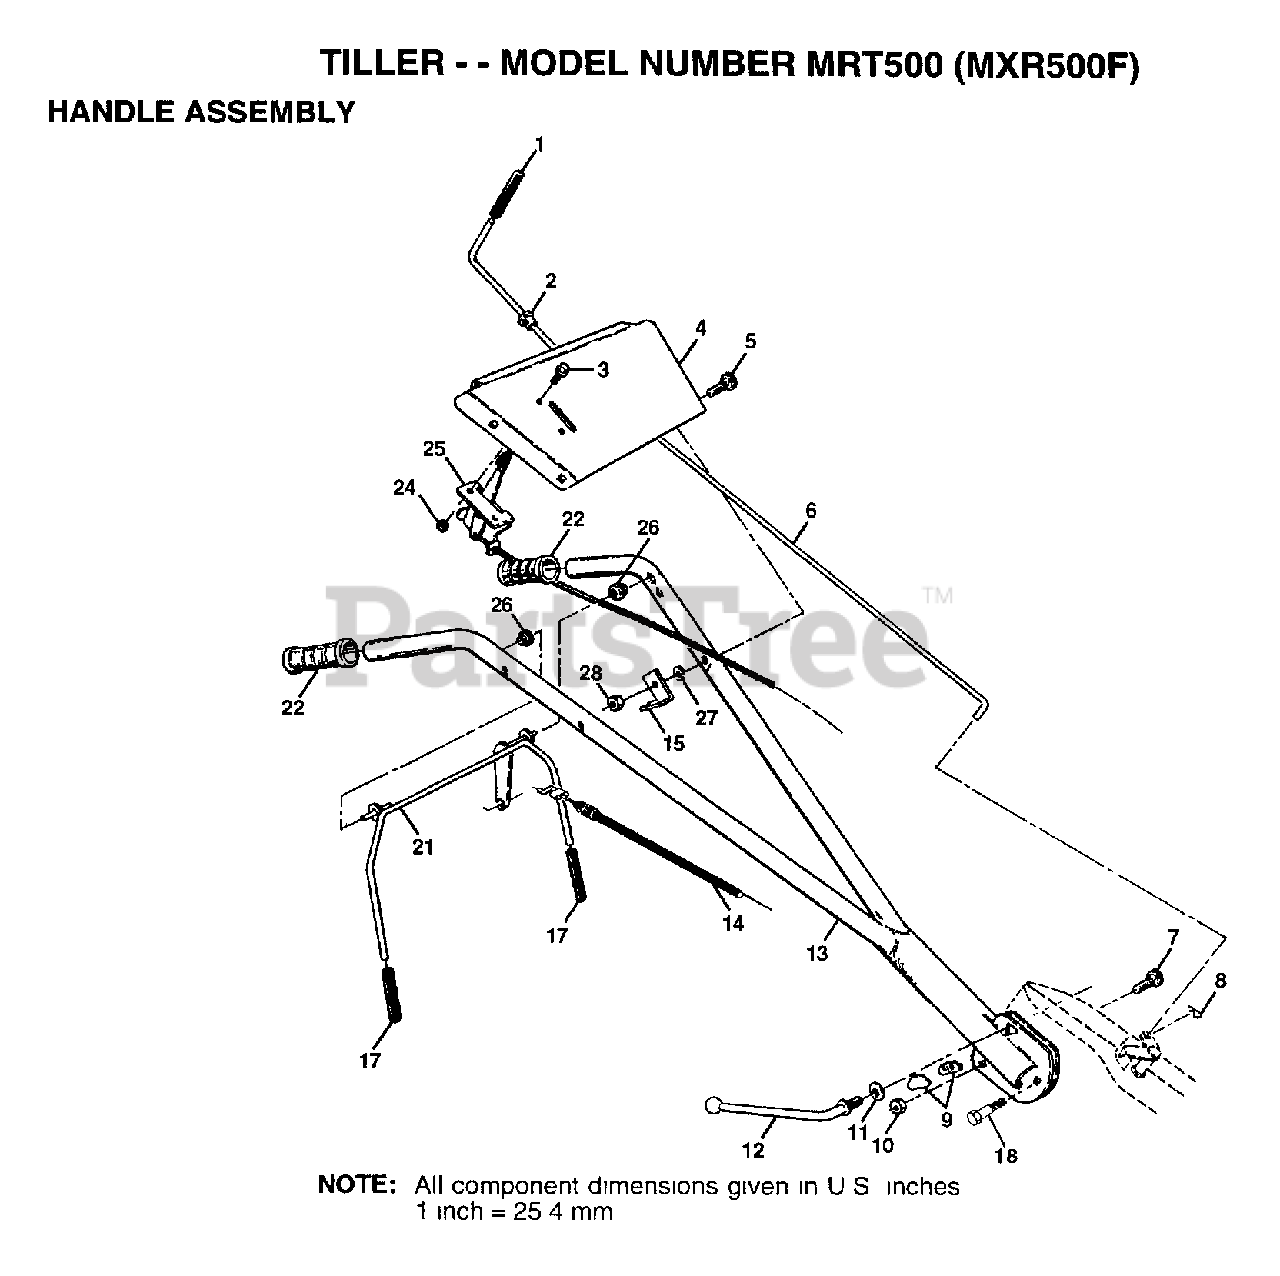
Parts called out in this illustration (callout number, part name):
1	GRIP TI
2	BUSHING
3	SCREW.PNHD.10-24
4	HANDLE BRACKET
5	BOLT CARRIAGE CRT
6	ROD SHIFT CRT
7	BOLT D
8	RETAINER M
9	LOCK CRT
10	LOCKNUT
11	WASHER CRT
12	LEVER LOCK CRT
14	CABLE.CLUTCH.Z-BE
15	BRACKET.CLUTCH.CA
17	GRIP BAR CRT
18	BOLT PIVOT
21	BAR.ASM.CNTRL.VPL
22	"GRIP,HANDLE"
23	NUT
25	"CONT,THROTTLE"
26	GROMMET.HANDLE.V-
27	LOCKWASHER
